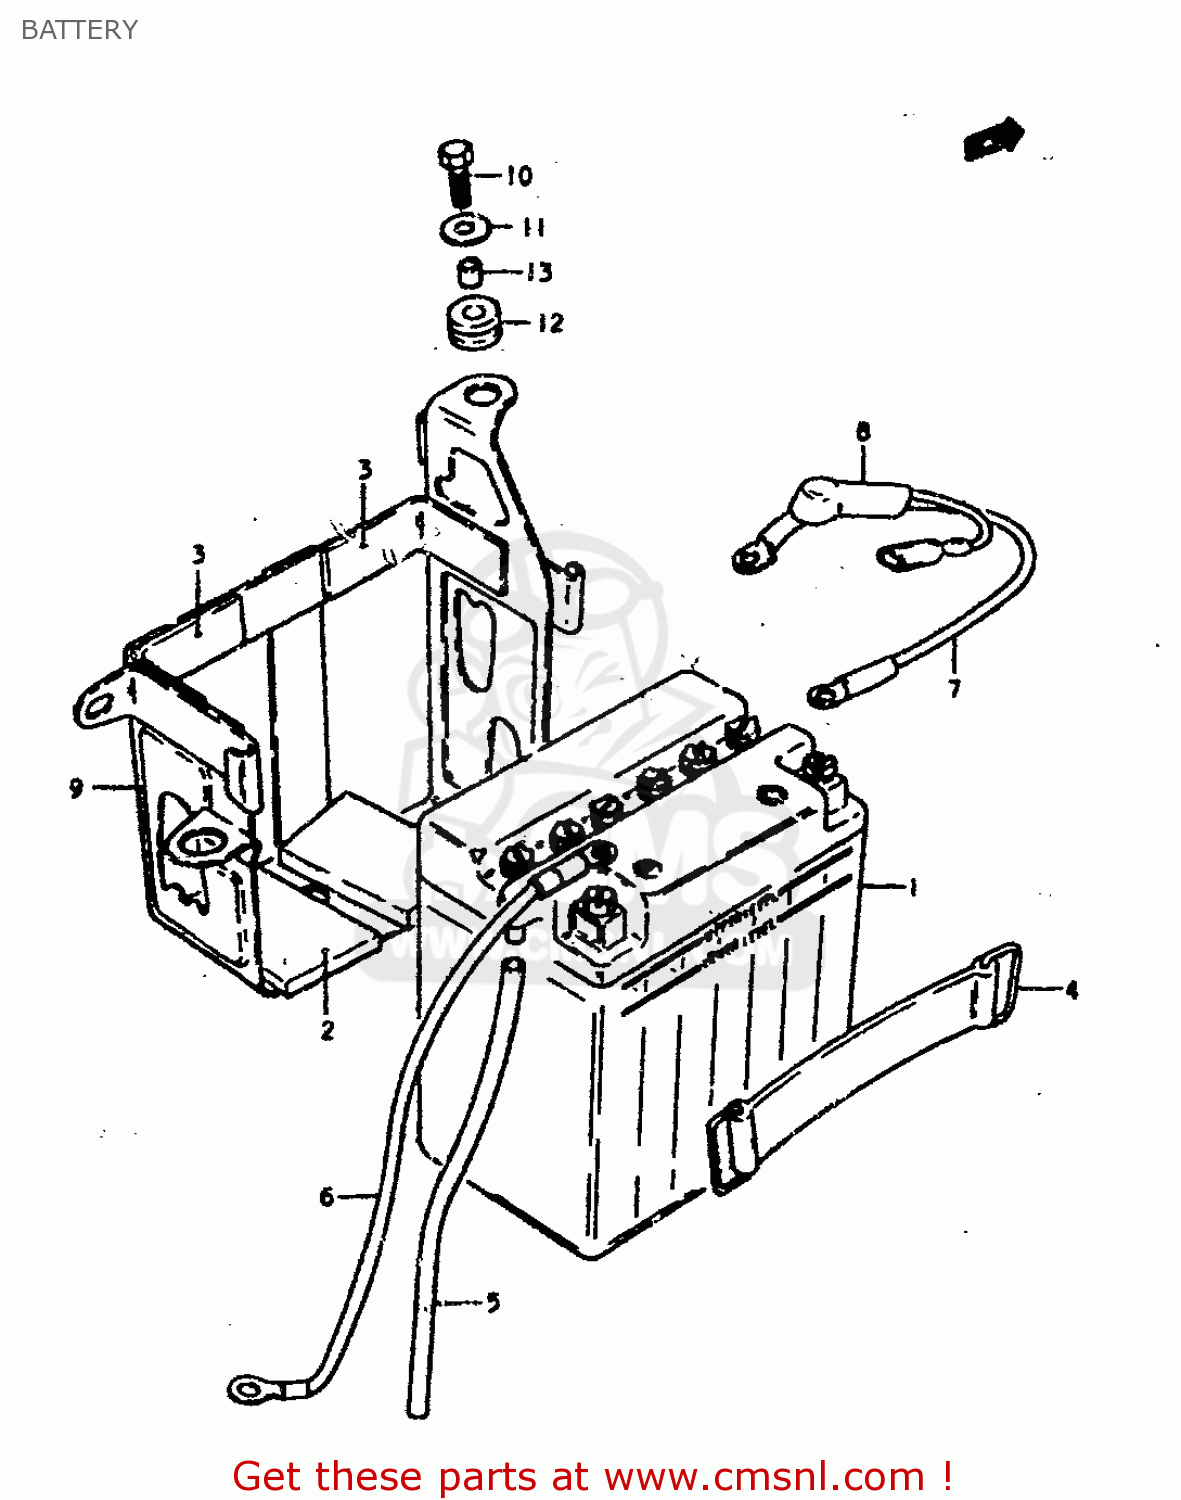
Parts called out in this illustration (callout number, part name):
1	BATTERY ASSY (12V)
2	CUSHION,BATTERY
3	PROTECTOR,20X9
4	BAND
5	HOSE,BATTERY EXHAUST
6	CORD,BATTERY MINUS
7	WARE,BATTERY PLUS
8	CAP,TERMINAL
9	HOLDER,BATTERY
10	BOLT
11	WASHER
12	CUSHION
13	SPACER (6.1X9X9)
